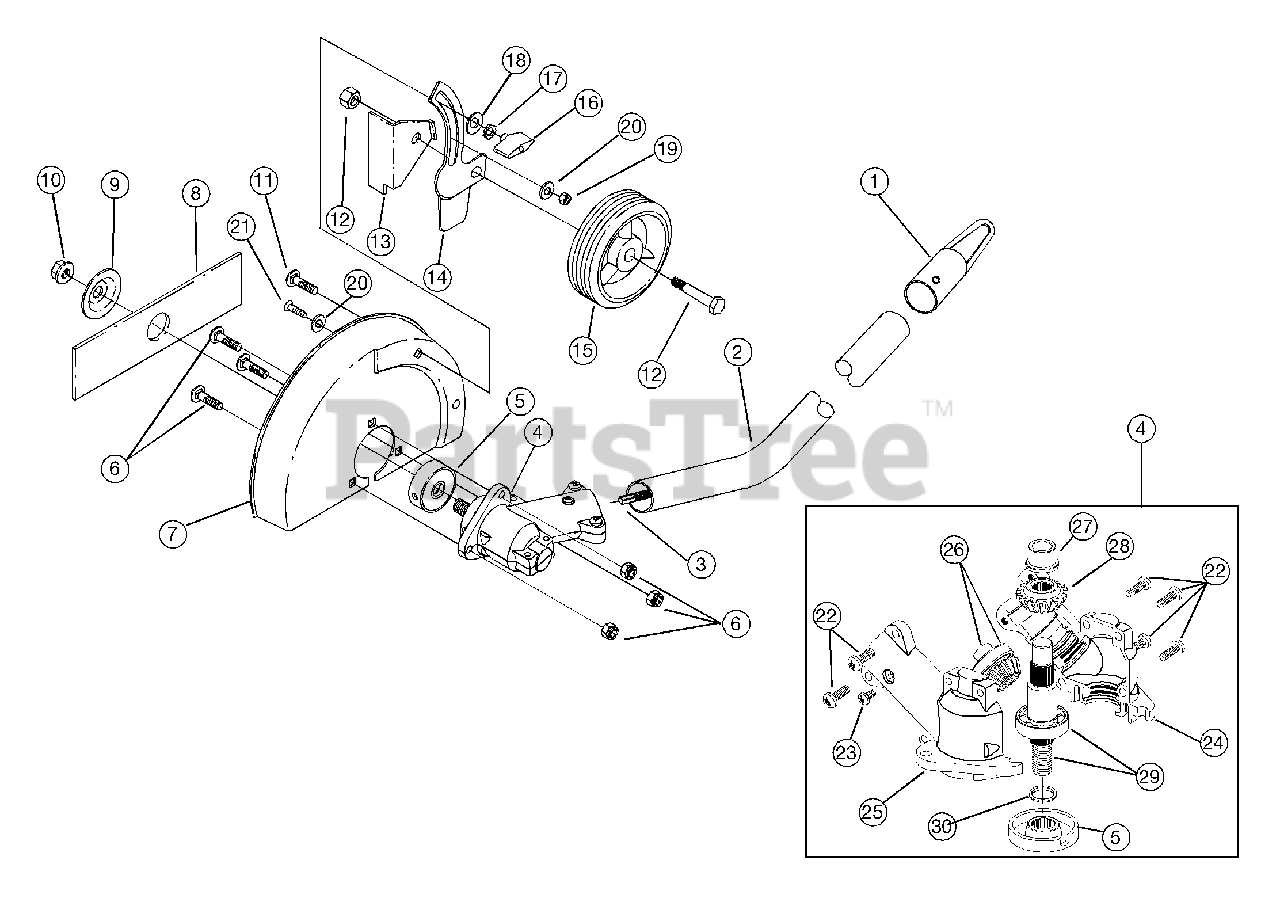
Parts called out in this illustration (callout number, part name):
1	Hanger
2	Drive Shaft Housing Assembly
3	Drive Shaft Assembly
4	Gearbox Assembly
5	Blade Driver
6	Shield Mount Screw Assembly
7	Blade Shield
8	Edger Blade
9	Retaining Washer
10	Lock Nut
11	Shoulder Bolt
12	Wheel Mounting Hardware
13	Deflector
14	Guide Bracket
16	Adjustment Knob
17	Lock Washer
19	Locknut
22	Gearbox Mounting Hardware
23	Anti-Rotation Screw
24	Left Housing
25	Right Housing
26	Pinion Gear Assembly
27	Output Shaft Bushing
28	Output Shaft Gear
29	Output Shaft Assembly
30	O-Ring
